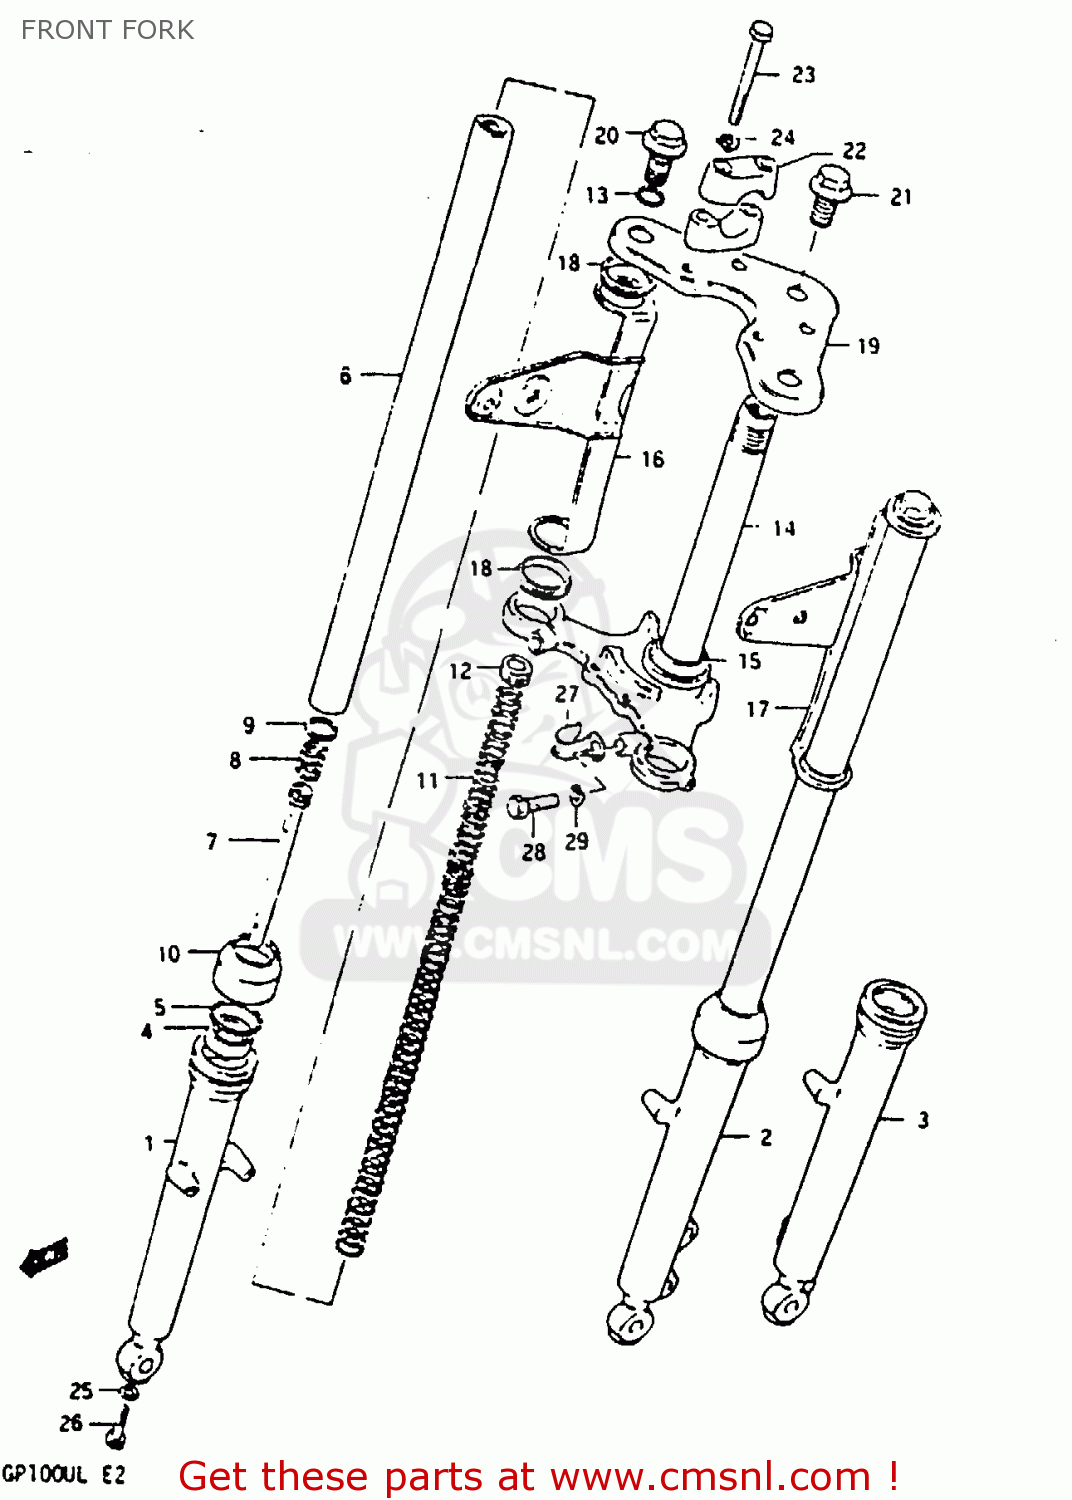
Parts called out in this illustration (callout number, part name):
1	OUTER TUBE, RH
2	OUTER TUBE, LH
3	OUTER TUBE, LH
4	SEAL,OIL
5	RING,SNAP
6	TUBE, INNER
7	CYLINDER
8	SPRING,REBOUND
9	RING
10	SEAL,DUST
11	SPRING
12	NUT
13	O-RING,FORK INNER TUBE
14	STEM, STEERING
15	RACE,STEERING OUTER LWR
16	BRACKET, HEADLAMP RH (BLACK)
17	BRACKET, HEADLAMP LH (BLACK)
18	GASKET (NAS)
19	HEAD, STEERING STEM (BLACK)
20	CAP
21	BOLT
22	HOLDER,HANDLE(BLACK)
23	BOLT
24	LOCK WASHER
25	GASKET (NAS)
26	BOLT,FORK CYLINDER(10X25)
27	CLIP,SPEEDOMETER CABLE
28	BOLT 10X30
29	WASHER,LOCK,10
